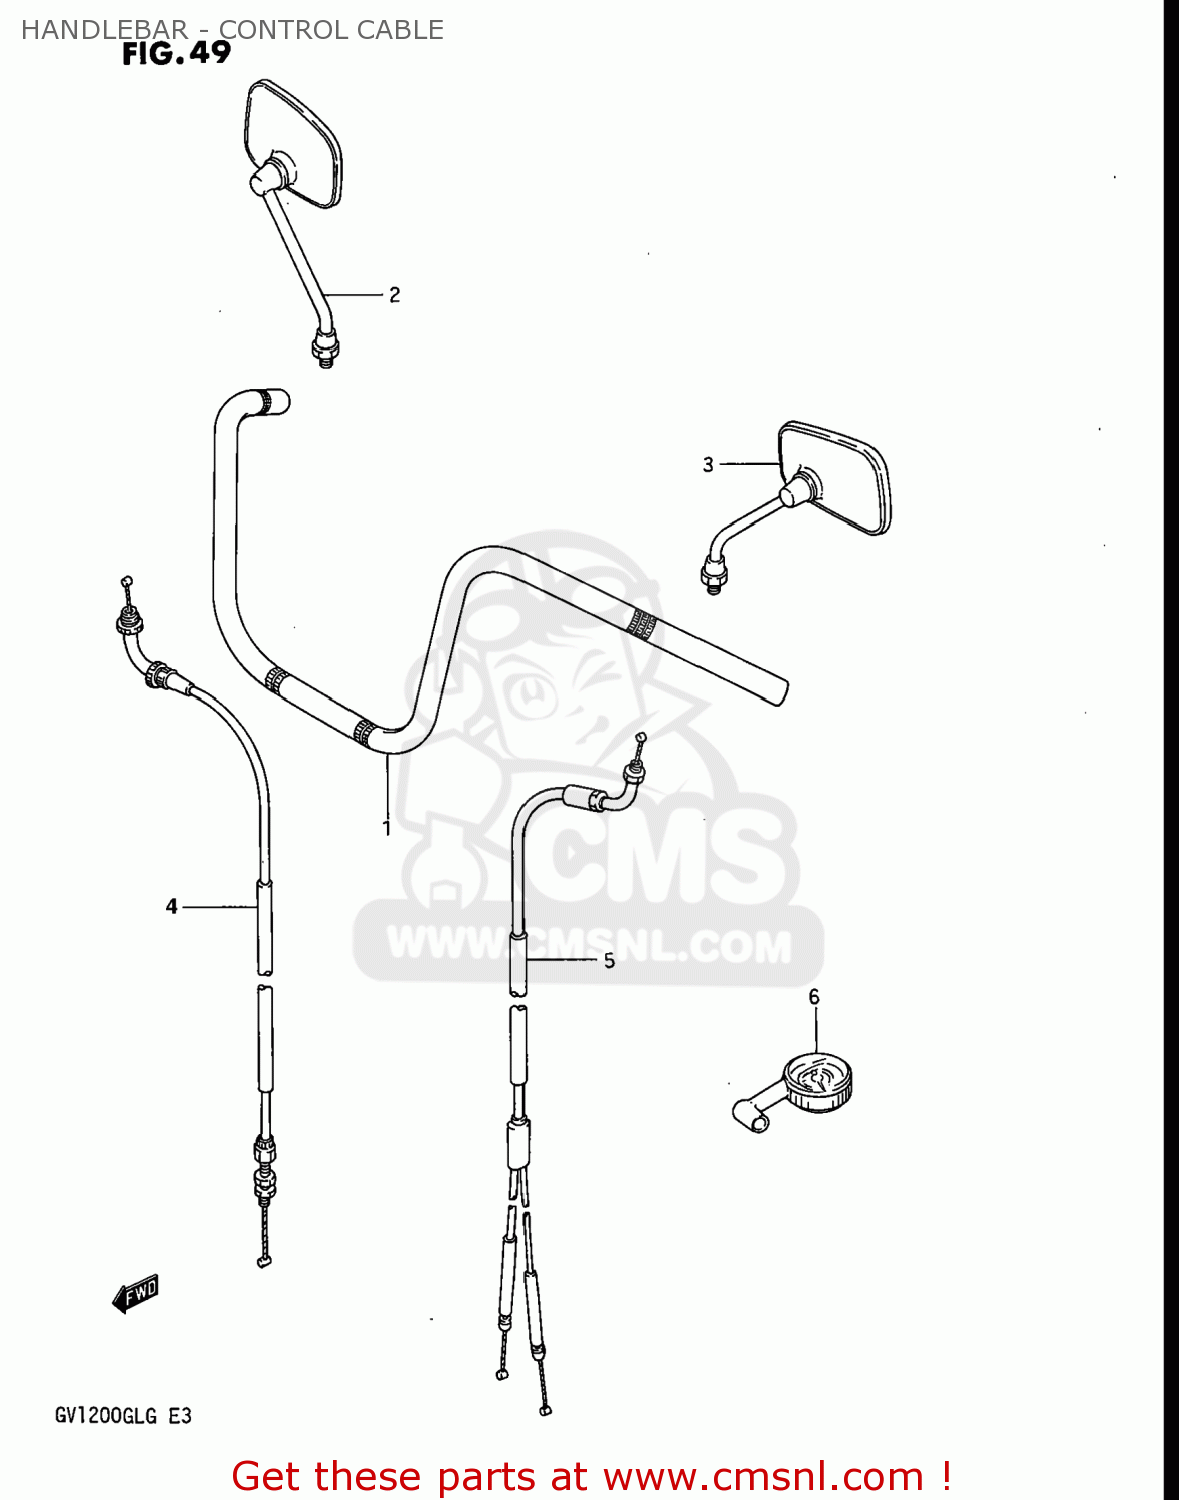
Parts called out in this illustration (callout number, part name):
1	HANDLEBAR,RIGHT
2	MIRROR ASSEMBLY,RIGHT
3	MIRROR ASSEMBLY,LEFT
4	CABLE ASSY,THROTTLE
5	CABLE COMP,STARTER
6	GAUGE ASSY,AIR PRESSURE
